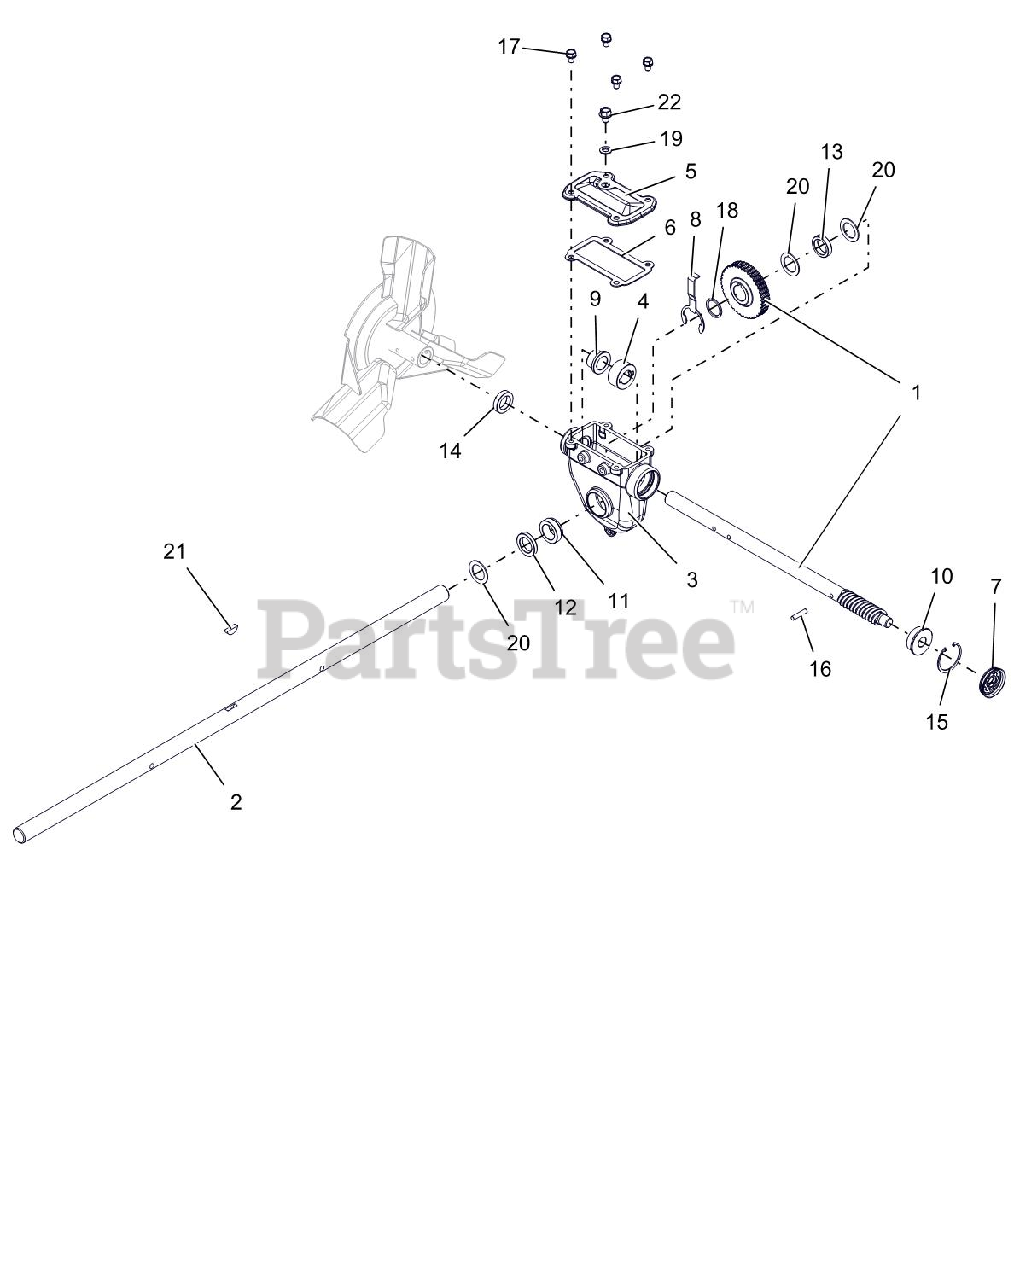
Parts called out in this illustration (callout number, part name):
1	ASSY, WORM SHAFT & GEAR
2	SHAFT, RAKE-36"
3	GEARCASE, LARGE MACHINED
4	THRUST COLLAR, .875"ID SLIPFIT
5	COVER, TOP - LARGE IRON
6	GASKET, TOP - LARGE GEARCASE
7	COVER, GEAR CASE 1.75"
8	BUSHING RETAINER, LARGE
9	BSHG-FLG .879X1.128X.75X1.45
10	BSHG-FLG .628X1.503X.58X1.725
11	BSHG-FLG LARGE, RIGHT
12	SEAL-OIL .999X1.500X.250 TBC29
13	SEAL-OIL .999X1.375X.312 TBC29
14	SEAL-OIL .873X1.375X.312 TBC29
15	RG-RTNG-INT 1.750X.062
16	PIN-STR .250X1.12 6150
17	BOLT, SEMS .31-18X.50 GR5 YWZC
18	WSHR-FL-STL 1.010X1.250X.068YZ
19	WSHR-BND-SEAL .38X.75X.11 GALV
20	WSHR-FL-STL 1.010X1.505X.062YZ
21	KEY-WDRF .25X.875 HRD #A
22	@SCR-ROLOK .38-16X.50 HWH YWZC
